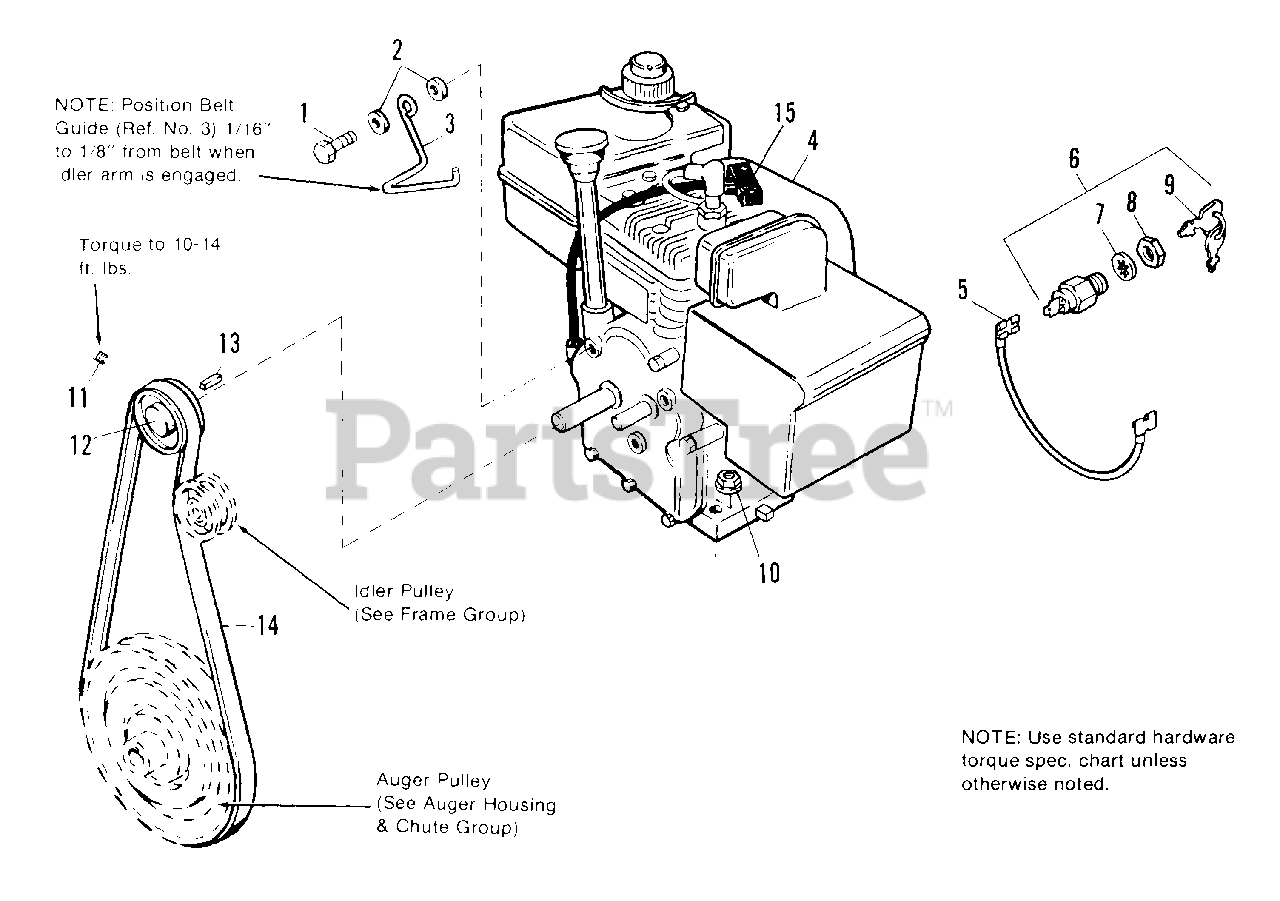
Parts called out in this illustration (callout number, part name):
1	CAPSCREW, Hex, 5/16-24 x 3/4
2	WASHER, 5/16
3	GUIDE, Belt, Engine Pulley
4	ENGINE, 3.5 HP (Tecumseh)
5	GROUND WIRE, Switch
6	SWITCH ASSY., Ignition w/Keys (Incl. Ref. Nos. 7, 8 & 9)
7	LOCKWASHER, 5/8
8	NUT, Hex, 5/8-32
9	KEY & RING ASSY.
10	NUT, Hex, Fl. Lock, 5/16-18
11	SETSCREW, Socket Hd., 5/16-18 x 5/16
12	PULLEY, Engine
13	KEY, Sq., 3/16x 3/16x 1
14	V-BELT, Auger Drive
15	ELECTRIC START
